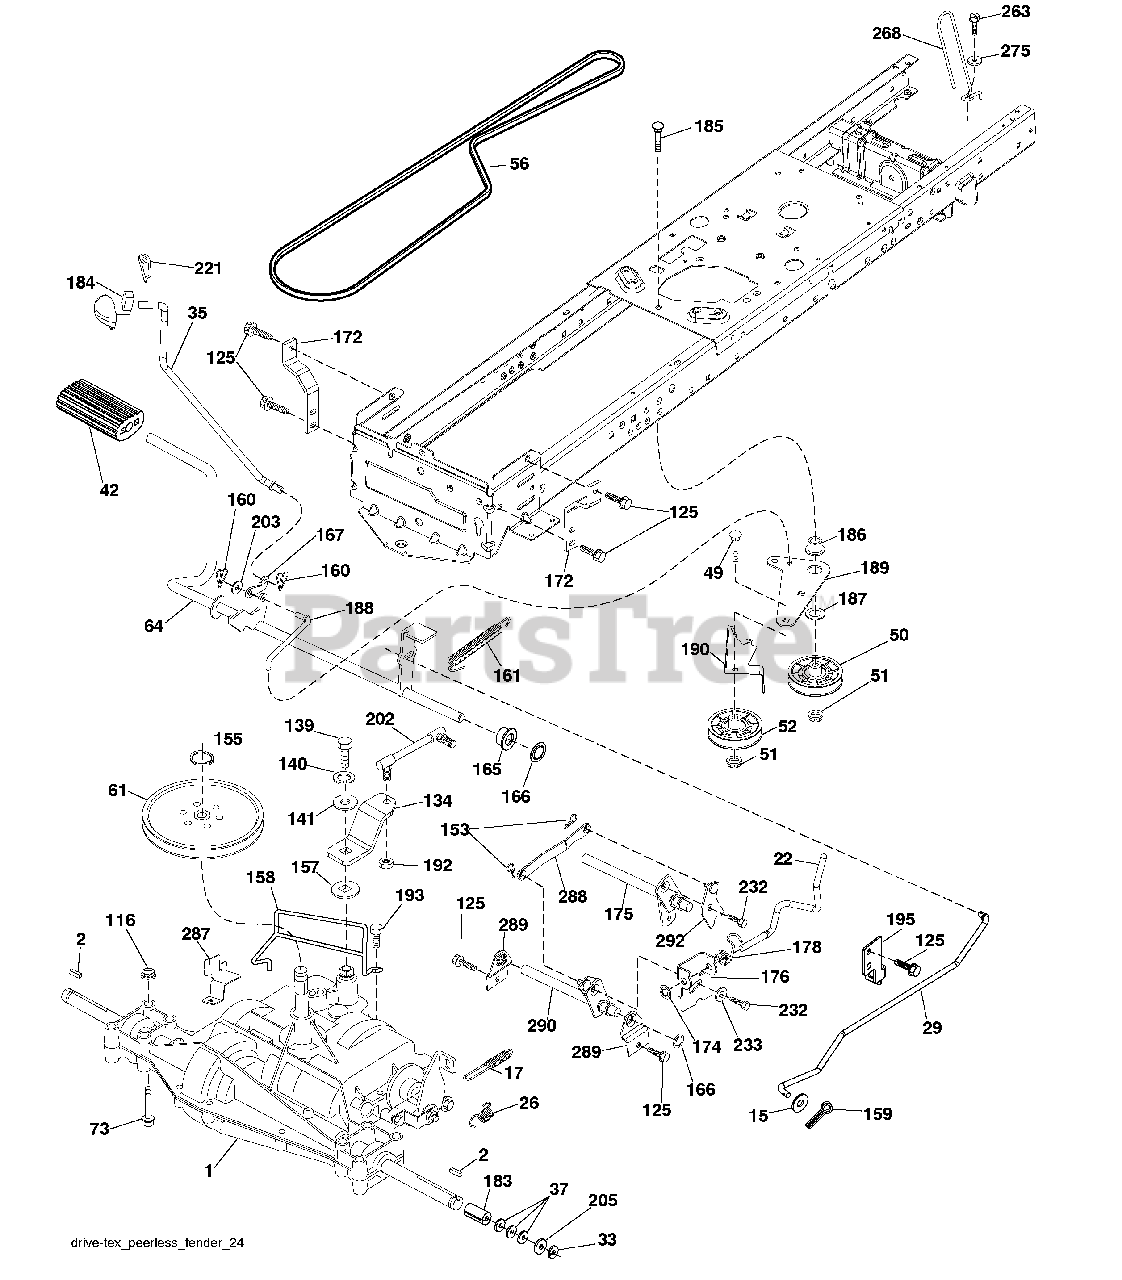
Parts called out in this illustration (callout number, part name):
2	Key Square
15	Washer 13/32 x 13/16 x 16 Ga.
17	Spring, Brake
22	Rod Shift
26	Spring Brake RTN
29	Rod, Brake
35	Rod, Brake, Park
37	Washer 25/32 x 1-1/4 x 16 Ga.
42	Cover, Foot Pedal
50	Pulley Idler Flat
51	Lock Nut 3/8-16
52	Idler V-Groove
56	V-Belt, Drive
61	Pulley Transaxle
64	Shaft Asm. Pedal Brake Control
73	Bolt 5/16-18 Gr. 5
116	Nut Lock Hex Flange 5/16-18
125	Screw 5/16-18 x 3/4
139	Bolt 1/4-20 unf Gr. 8 w/Patch
140	Washer Lock Hvy Helical 1/4
141	Washer 9/32 x 3/4 x 10 Ga.
153	Retainer Spring 1"
155	Ring Retainer
157	Washer Plate Shf
158	Keeper T/A
159	Pin Cotter 1/8 x 3/4
160	Retainer Clip
161	Spring, Return, Clutch
165	Busing Shaft Brake Hand Control
166	Nut Push .625
167	Latch Brake Parking
172	Strap Torque LH
175	Shaft Asm Shift
176	Arm Clevis Rod Shift
178	Spring Shift
183	Spacer, Axle
184	Handle Parking Brake
186	Spacer Retainer
187	Washer
188	Link Clutch Ground Drive
189	Bellcrank Ground Drive
190	Keeper Bellcrank Ground Drive
192	Nut Lock Center 1/4-28
193	Screw 5/16-18 x 3/4
195	Bracket Brake Rod
202	Link Shift
203	Washer 11/32 x 11/16 x 16 Ga.
205	Washer 25/32 x 1-5/8 x 16 Ga.
221	Retainer Spring Clip Handle
232	Bolt 7/16-14 x 1 Gr. 5
233	Washer Serrated
263	Screw Hexwsh THDR 3/8-16 x 3/4
268	Washer 13/32 x 1 x 14 Ga.
275	Guard Muffler
287	Keeper Pulley Transaxle
288	Link Shift Slave
289	Bracket Support Shift Outer
290	Shaft Asm. Shift Rear
292	Plate Asm. Shift
